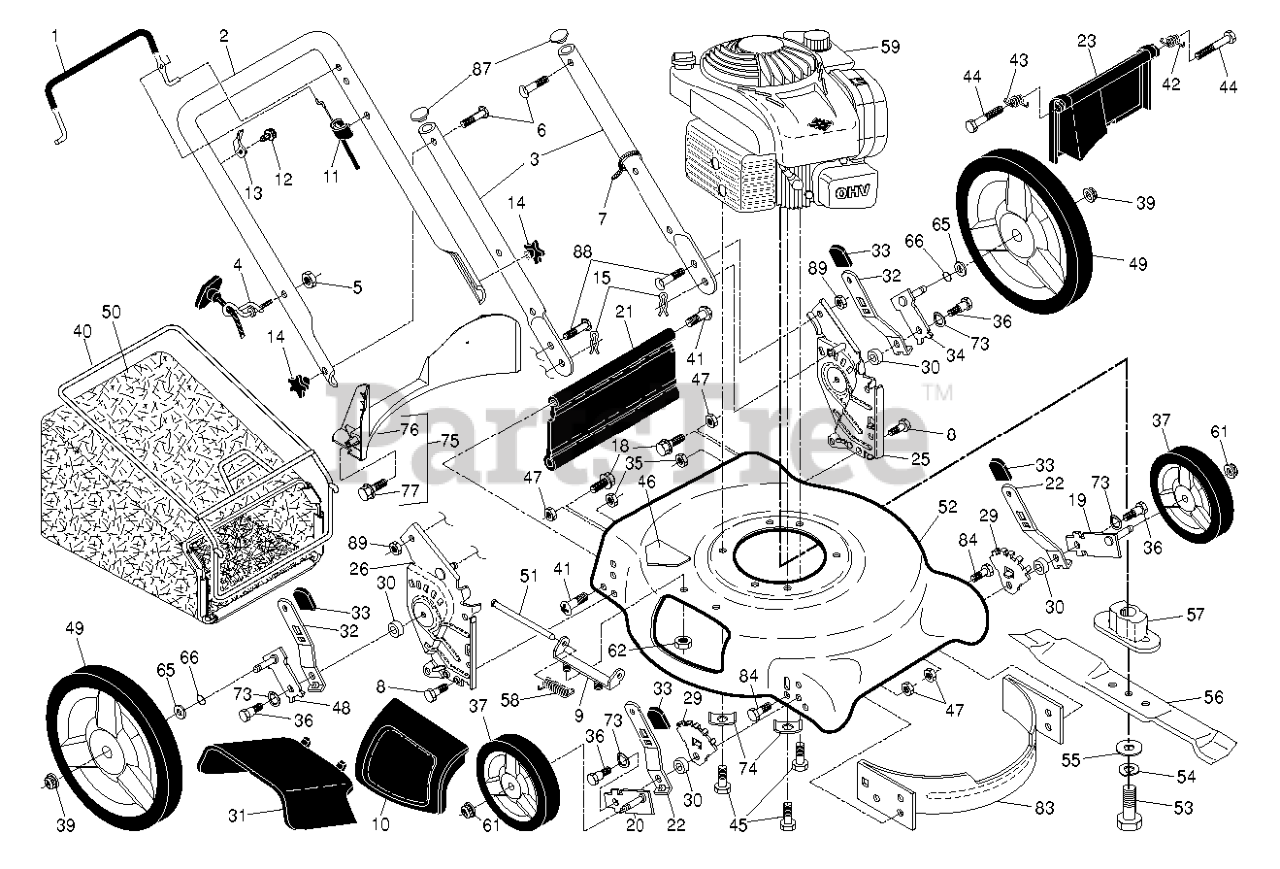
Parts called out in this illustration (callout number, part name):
1	RP BAIL.OVER.MOLD.STRAIGHT.ORG
2	HANDLE.UP.DST.SS/VS.FG/RGD.CRE
3	HANDLE.LOWER.DOME.BT.GREY
4	RB GUIDE.ROPE.STD.BLK.ZIN WSL
5	NUT
6	BOLT, HANDLE 5/16-18X1.75
7	TIE GUIDE
8	BOLT.FIN.HEX.5/16-18X3/4
9	BRACKET.ASM.HOUSING.EZ.MUL
10	DOOR.MULCH.21".REAR.PUSH.GRAY
11	CONTROL.ZONE.ASM
13	BRACKET.UPSTOP.RT
14	KNOB.HANDLE.PLASTIC.STAR.BLACK
15	HAIRPIN COTTER
18	SCREW 1/4X20
19	AXLE ARM ASSY FRONT LH
20	AXLE ARM ASSY FRONT RH
21	RP_KIT.SKIRT.21 DOMED.W/LIP
22	SELECTOR SPRING, FRONT
23	DOOR.REAR.21.DOMED.498
25	BRACKET.ASM.HAND.HW.21.LT.GREY
26	BRACKET.ASM.HAND.HW.21.RT.498
29	WHEEL ADJ BRACKET FRONT
30	SPACER.HEIGHT.ADJUSTER
31	DEFLECTOR.CLIPPING.21.GREY
32	SPRING.SEL.22.ECON.HI-WHL.RATO
34	AXLE ARM ASSY REAR LH
35	NUT.FLANGE.HEX.5/16X18.BLACK
36	SHOULDER BOLT 5/16-18
37	WHEEL AND TIRE ASSY, REAR
39	NUT.HEX.FLANGE.3/8-16.LOCKNUT
40	FRAME.BAG.21.REAR.DOMED.PUSH
41	SCREW.1/4-20X21/4.HEX.
42	SPRING.LH.22.REAR.DOOR.EZ.EMPT
43	SPRING.RH.22.REAR.DOOR.EZ.
45	BOLT 3/8-16X1-1/8
46	DANGER DECAL
47	NUT.LOCK.5/16-18
48	AXLE ARM ASSY REAR RH
49	WHEEL.12 X 1.75 CFH3SPK.RAD3
50	GBAG.23230247.SILVER.HUSQ.BLUE
51	ROD.HINGE.COMBI-C
52	HOUSING.21.M/C.DOME.ORANGE
53	SCREW, HEX HD 3/8-24 X 1-3/8
54	LOCKWASHER
55	WASHER,HARDEN
56	BLADE.21.PUSH/RWGD/FWGD
57	ADAPTOR.BLADE.7/8
58	TORSION SPRING
61	NUT.HEX.FLANGE.3/8-16.LO(3 2)
62	LOCKNUT.NYLOC.1/4-20
65	WASHER.FLAT.1/2
66	O-RING..070X.487.NEOPRENE
73	WASHER.CURVED.CYLINDRICAL
74	WASHER.ENGINE.BZP
75	KIT.BAFFLE.REAR.PLASTIC.21.RD
76	BAFFLE.REAR.PLASTIC.21.RD.ECON
77	SCREW.HX.13X.750
83	BAFFLE.FRONT.21.DOME.US
84	BOLT.5/16HEX.WHS.HD
87	PLUG.PLASTIC.7/8".14-20.GAUGE
88	BOLT
89	LOCKNUT-FLANGE 5/16-18
